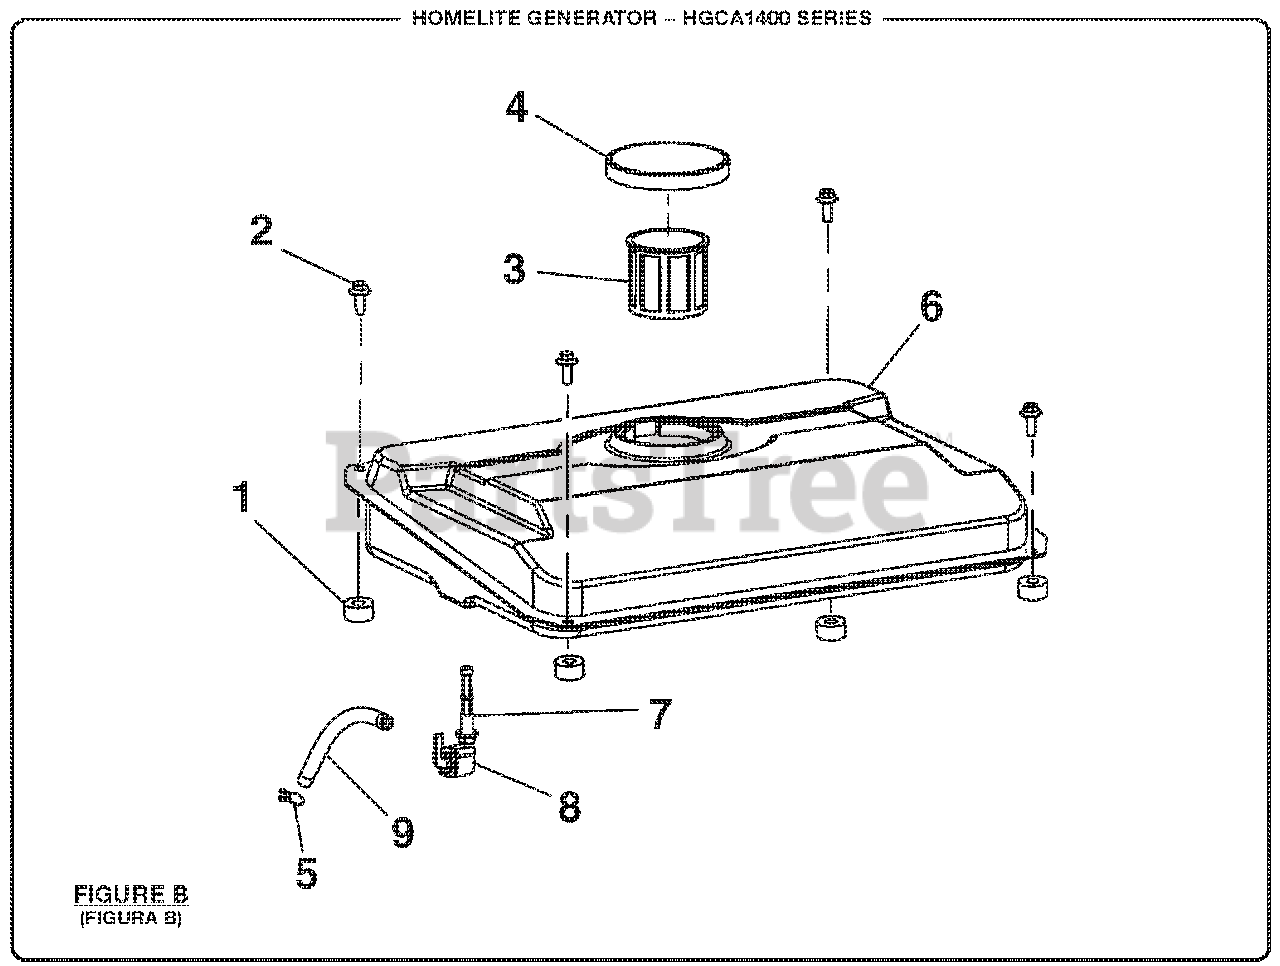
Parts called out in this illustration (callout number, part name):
2	Bolt (M6 x 25 mm)
3	Fuel Strainer
7	Fuel Filter
